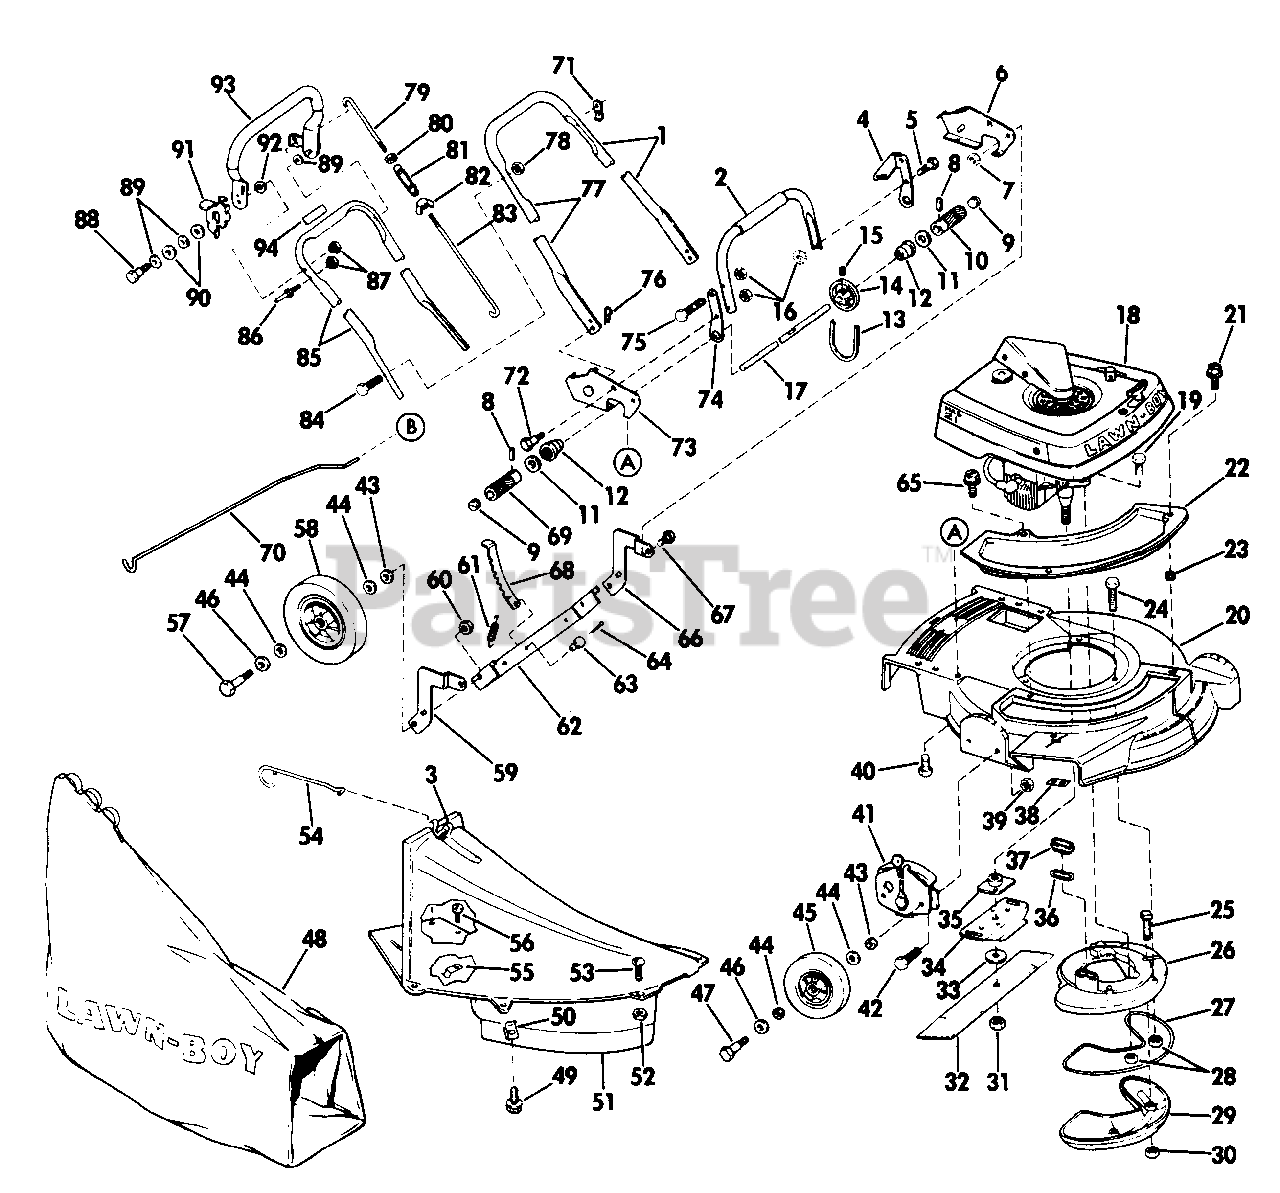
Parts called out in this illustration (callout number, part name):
1	Handle-Lower
2	Connect Link & Grip Assembly
3	Clip Assy.-Chute (Plastic)
3	Clip Assy.-Chute (Metal)
4	Bracket-L.H.
5	Shoulder Bolt
6	Handle Bracket Assembly L.H.
7	Nut
8	Roll Pin-Roller to Shaft
9	Plug-Grease, Roller
10	Drive Roller-L.H.
11	Washer
12	Sleeve & Bearing Assembly
13	V-Belt-Driven
14	Pulley-Driven
15	Set Screw
16	Nut
17	Driveshaft
18	Engine-Model D-448
19	Screw-Crankcase to Muffler Plate
20	Housing Assembly 21"
21	Hex Head Screw
22	Cover-Chute Opening (Plastic)
23	Grommet
24	Screw-Muffler Plate to Housing
25	Screw-Muffler to Muffler Plate
26	Plate-Muffler
27	Gasket-Muffler
28	Nut-Nylock
29	Muffler
30	Nut-Muffler Mounting
31	Nut-Blade
32	Blade, 21"
33	Washer-Blade
34	Stiffener-Blade
35	Collar & Plate Assembly
36	Gasket-Exhaust
37	Sleeve-Muffler Exhaust
38	Speed Nut
39	Nut-Height Adj. Mounting
40	Screw-Handle Bracket
41	Height Adjustment Assy.
42	Screw-Height Adjust to Housing
43	Washer
44	Felt Washer
45	Wheel & Tire Assembly 6"
46	Washer
47	Wheel Bolt-Front
48	Grass Bag
49	Screw
50	Speed Nut
51	Skirt Assembly
52	Nut
53	Screw
54	Wheel Guard Assembly
55	Speed Nut
56	Screw
57	Wheel Bolt-Rear
58	Wheel & Tire Assembly 8"
59	Wheel Bracket-Right Rear
60	Nut-Rear Wheel Bolt
61	Spring-Height Adjust
62	Bracket
63	Pin
64	Cotter Pin
65	Screw
66	Wheel Bracket-L-H. Rear
67	Bolt-Shoulder
68	Height Adjust Lever
69	Drive Roller-Right
70	Rod & Clip Assembly
71	Clip-Bag Support Rod
72	Shoulder Bolt
73	Handle Bracket-Right
74	Bracket
75	Screw
76	Hair Pin
77	Handle-Lower
78	Nut-Handle
79	Rod-Control, Upper
80	Nut-Jam
81	Turn Buckle
82	Wing Nut
83	Rod-Control, Lower
84	Screw-Handle
85	Handle-Center
86	Lockout Pin Assembly
87	Nut
88	Bolt
89	Washer
90	Wave Washer
91	Clip-Lockout
92	Washer
93	Handle & Grip Assembly
94	Decal-Handle
